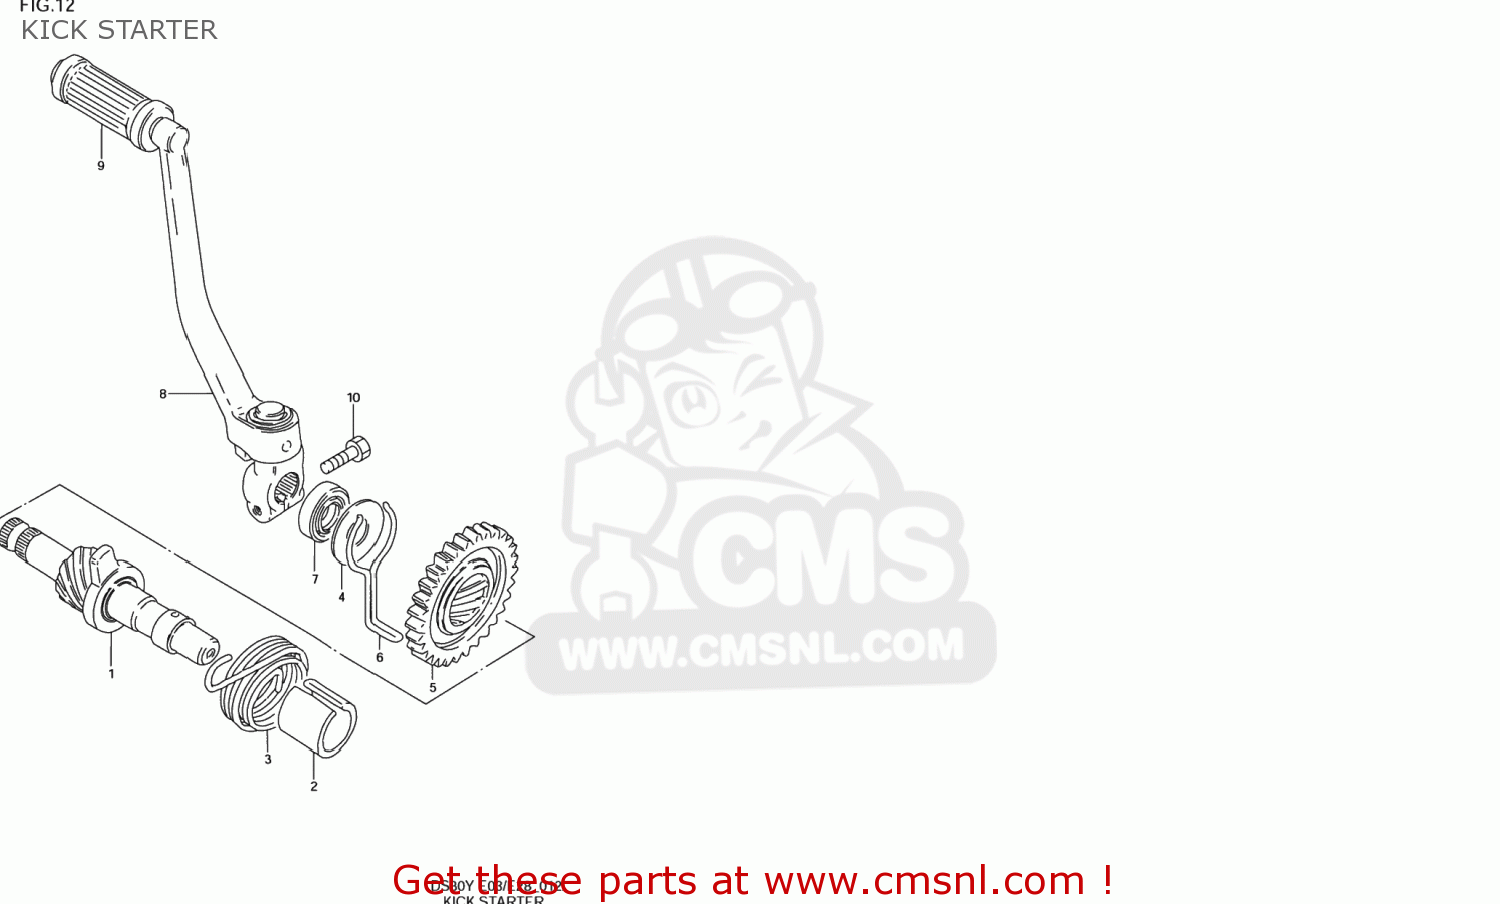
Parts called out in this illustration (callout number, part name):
1	SHAFT,KICK STARTER
2	GUIDE,KICK STARTER SFT SPRING
3	SPRING
4	WASHER
5	GEAR,KICK STARTER DRIVE(NT:30)
6	RETAINER,SNAP
7	SEAL,OIL(14X24X6)
8	LEVER ASSY,KICK STARTER
9	RUBBER,KICK STARTER PEDAL
10	BOLT
